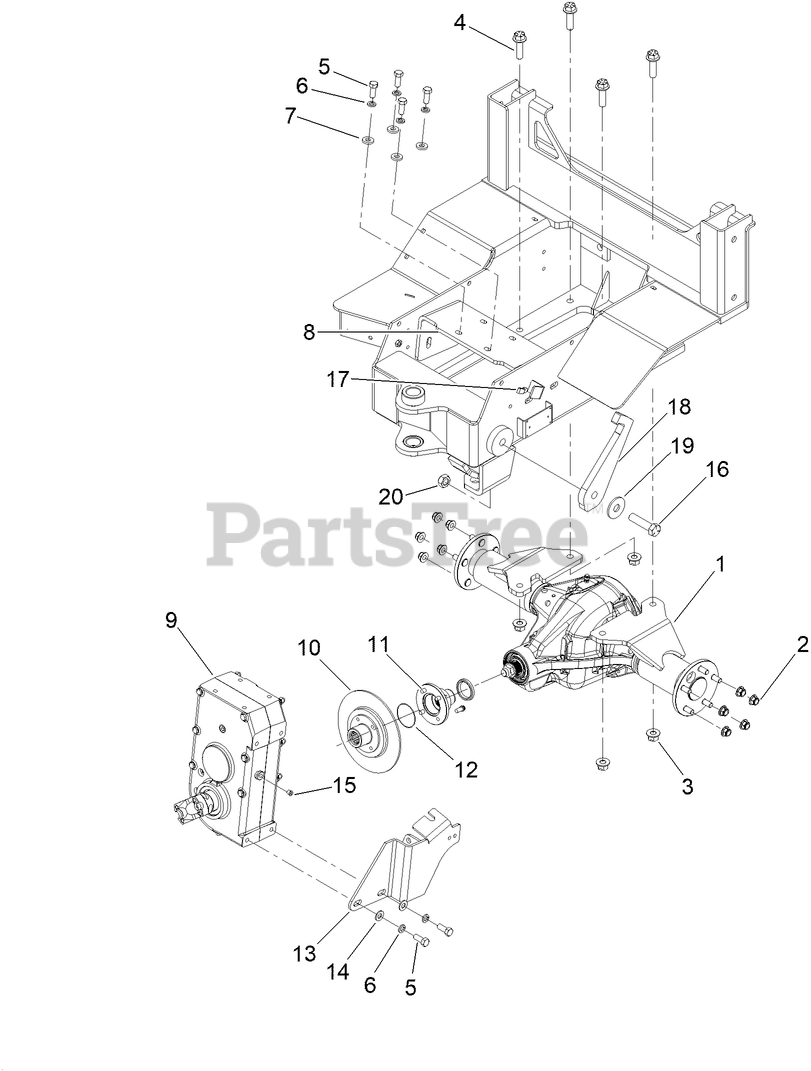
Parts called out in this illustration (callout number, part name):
1	DANA 44 ASSEMBLY
2	NUT-HHF
3	FLG LOCKNUT (5/8-NC, GR G)
5	SCREW-HH
6	WASHER-LOCK
7	WASHER-HARDENED
8	MOUNT-GEARBOX
9	TRANSMISSION ASM
10	FLANGE-COMPANION
11	SCREW-12 PT FLANGE
12	O-RING(-36), D70
13	BRAKE MOUNT
14	WASHER-FLAT
16	SCREW-HH
17	CLIP ON CLAMP
18	LEVER-FRAME LOCK
19	WASHER-FLAT
20	NUT-LOCK, NI
